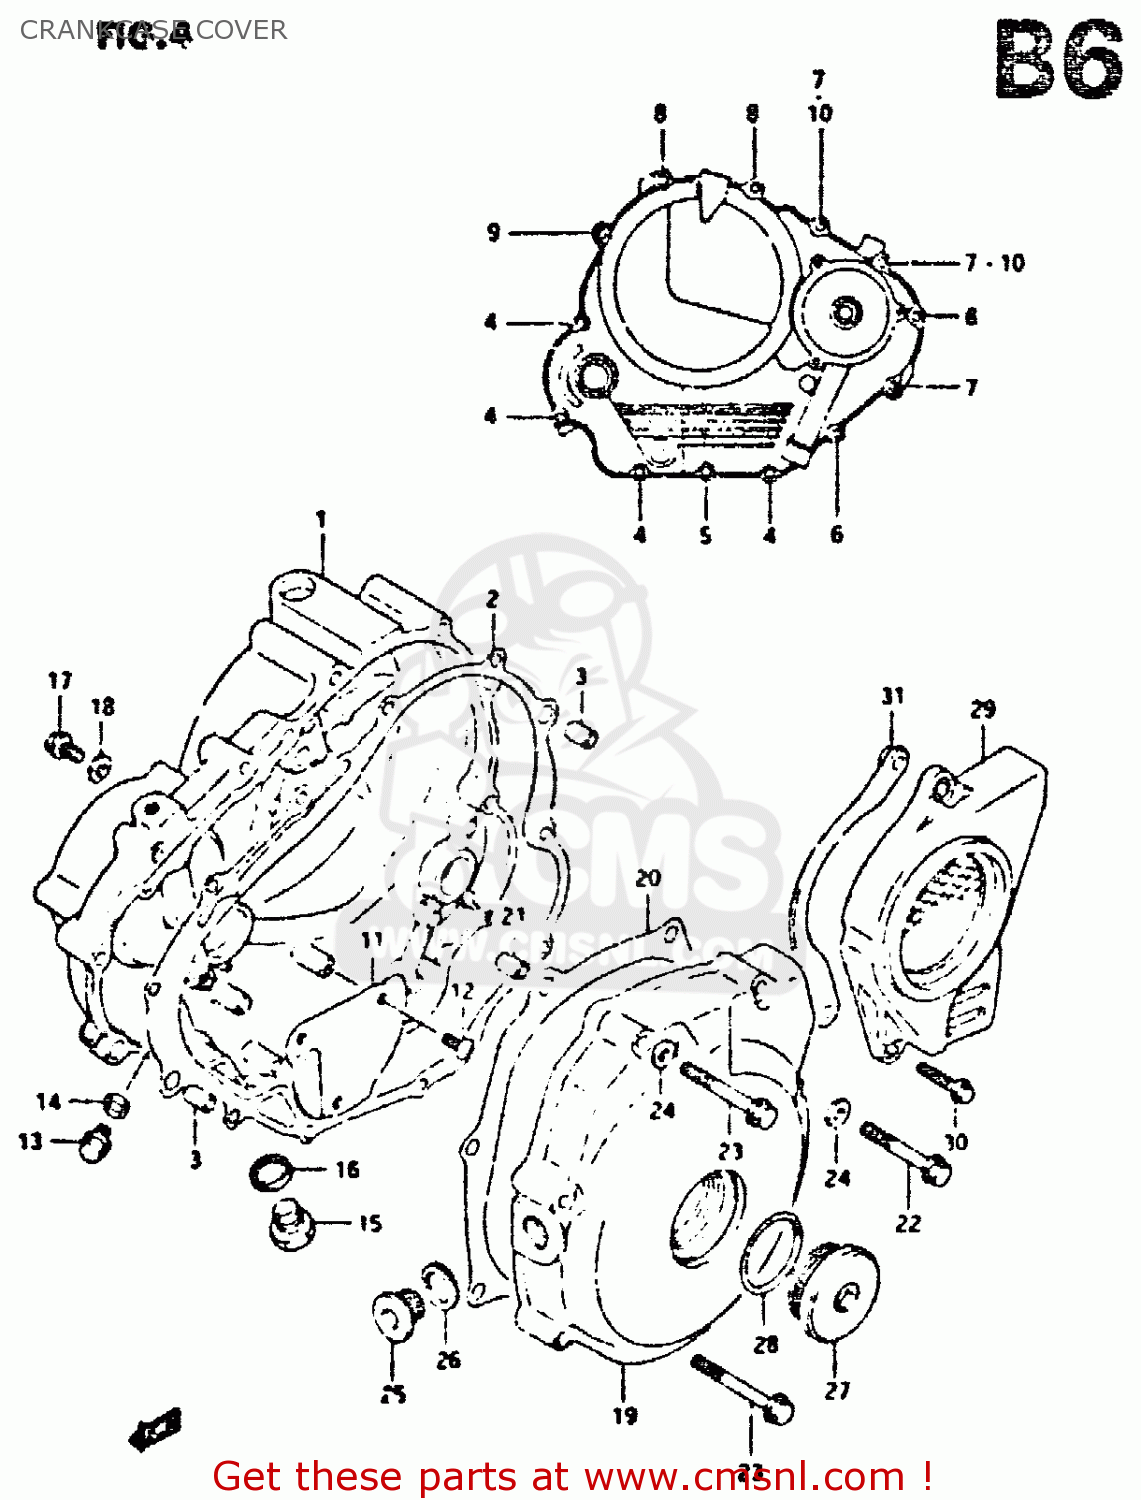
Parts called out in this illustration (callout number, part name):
1	COVER,CLUTCH
2	GASKET,CLUTCH COVER (NAS)
3	PIN
4	BOLT
5	BOLT
6	BOLT
7	BOLT
8	BOLT
9	BOLT
10	GASKET(5.8X13X1.2) (NAS)
11	SEPARATOR,OIL RETURN
12	SCREW
13	BOLT(6X8)
14	GASKET(6.2X11X1).2 (NAS)
15	PLUG,14X12
16	GASKET(14X19.2X2) (NAS)
17	SCREW (6X10)
18	GASKET(5.8X13X1.2) (NAS)
19	COVER,MAGNETO
20	GASKET,MAGNETO COVER (NAS)
21	PIN
22	BOLT
23	BOLT
24	GASKET(5.8X13X1.2) (NAS)
25	PLUG,14X12
26	GASKET(13.8X18.8X4.8) (NAS)
27	PLUG(SILVER)
28	O RING(D:3.1,ID:32.7)
29	COVER,ENGINE SPROCKET
30	BOLT
31	PLATE,FR CHAIN GUIDE
